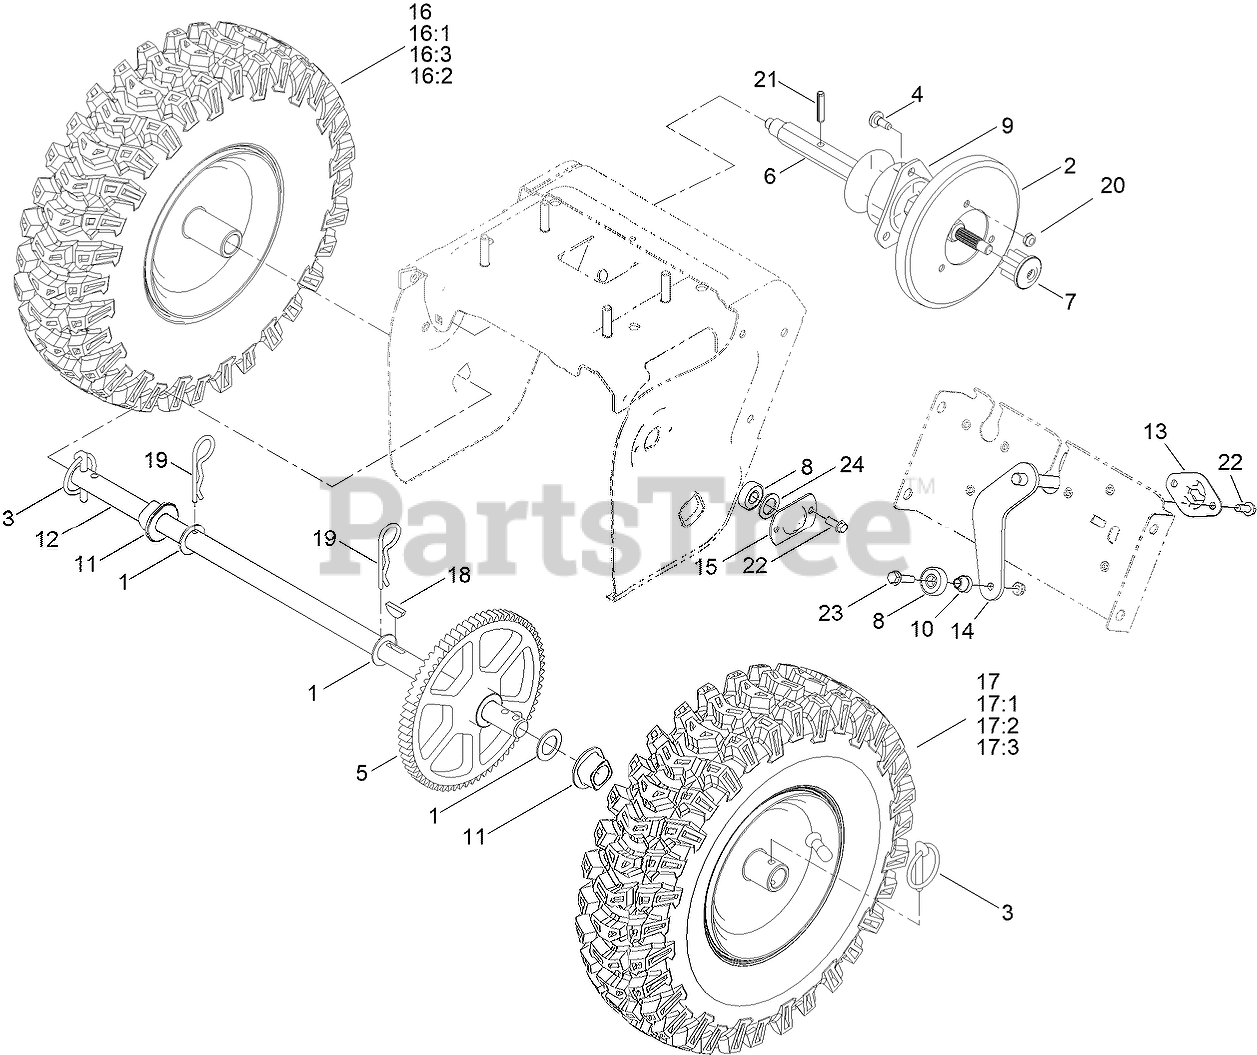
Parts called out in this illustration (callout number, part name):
1	WASHER-THRUST
2	WHEEL-FRICTION
3	KLIK PIN ASM
4	SCREW-SHOULDER
5	GEAR-AXLE
6	SHAFT-HEX
7	GEAR-PINION, 8 TOOTH
8	BEARING-BALL
9	TRUNNION
10	SPACER-PLATE, SHIFT
11	BUSHING-AXLE
13	RETAINER-PLATE, SHIFT
14	SHIFT PLATE ASM
15	RETAINER-BEARING
16	LH WHEEL AND TIRE ASM
16:1	WHEEL (15X4 TIRE)
17	RH WHEEL AND TIRE ASM
17:1	WHEEL (15X4 TIRE)
18	KEY-WOODRUFF
19	PIN-HAIR
20	NUT-HEX
21	PIN-ROLL, SLOTTED
22	SCREW-HWH
23	SCREW-HWHTF
24	WASHER-RUBBER
